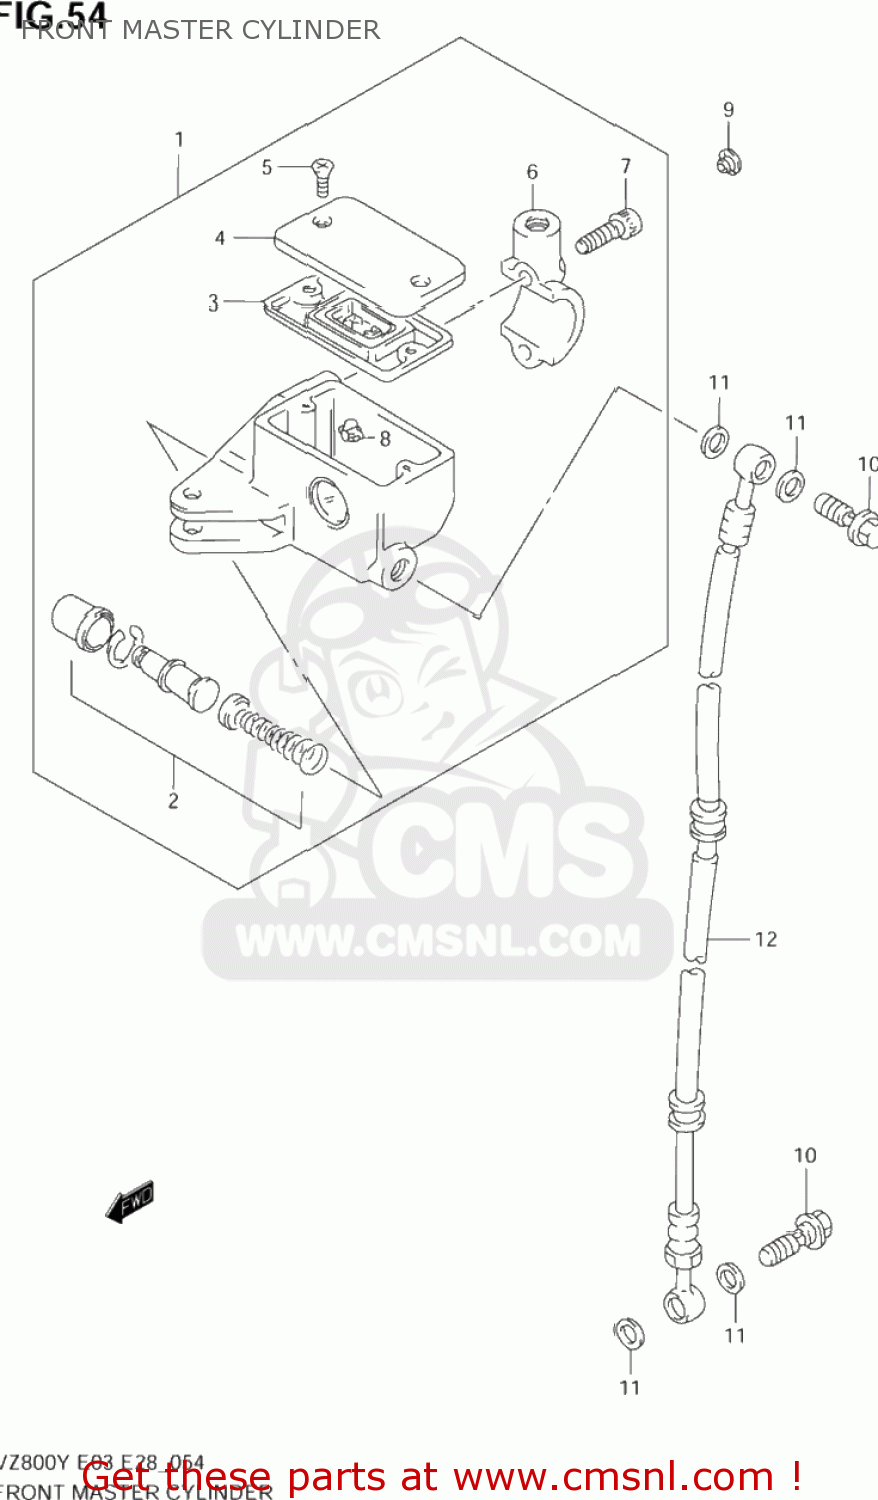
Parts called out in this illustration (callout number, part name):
1	CYLINDER ASSY,FR MASTER
2	PISTON/CUP SET
3	4
4	CAP
5	SCREW
6	HOLDER
7	BOLT
8	PROTECTOR
9	CAP(OD:10)
10	BOLT UNION
11	WASHER(10X15X1.5)
12	HOSE,FR BRAKE
